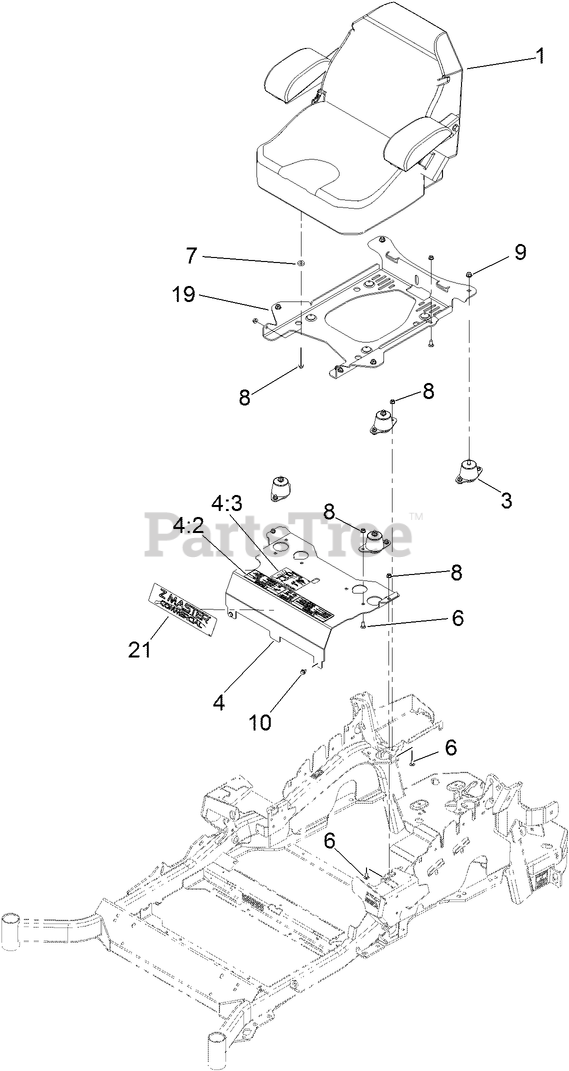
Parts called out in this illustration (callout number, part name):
1	SEAT-STANDARD
3	ISOLATOR-SEAT
4	MOUNT-SEAT
4:2	DECAL-CONSOLE
4:3	DECAL-SERVICE AID
6	SCREW-CARR
7	SPACER-PIN, MOUNTING
8	NUT-HF, NI
9	NUT-HF, NI
10	SCREW
19	SEAT BASE ASM
